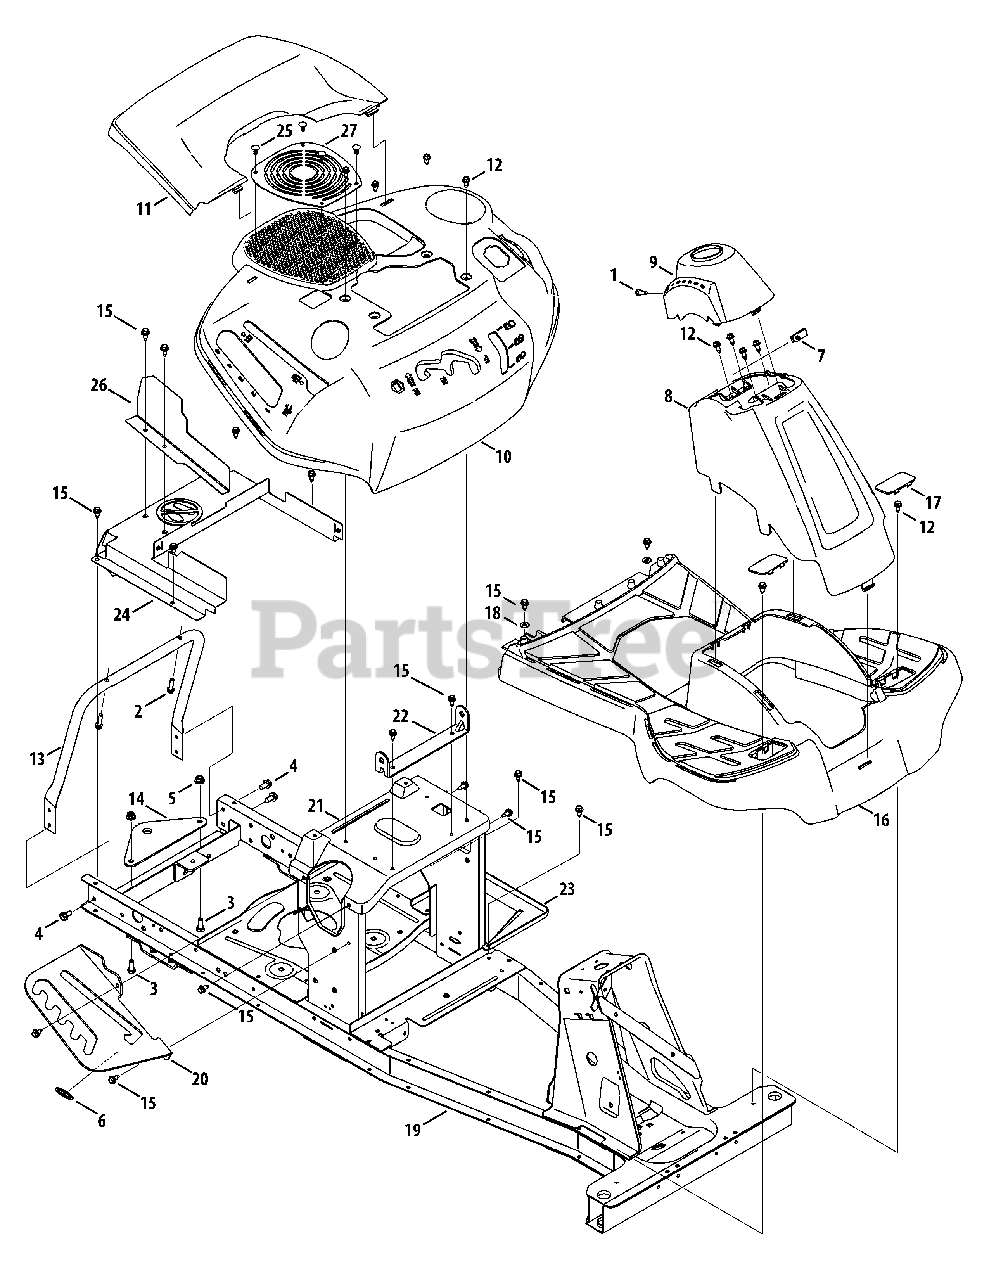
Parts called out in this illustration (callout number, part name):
1	Machine Screw, 1/4-20, 0.750
2	Hex Screw, 1/4-15, 1.000
3	Hex Head Screw, 5/16-18, .75
4	Tap Screw, 5/16-18, .750
5	Flange Locknut, 5/16-18
6	Speed Nut
7	U-type Speed Nut, 1/4-20
8	Column Cover
9	Steering Column Cap
10	Fender, (MTD Eng. 4P90JU)
11	Rear Cover
12	Shoulder Screw, .368 X.113: 1/4-20
13	Rear Cover Support Tube
14	Hitch Plate
15	Tap Screw, 1/4-20, .625
16	Running Board
17	Running Board Plug
18	Flat Washer, .250 x .630 x .052
19	Frame Assembly
20	Deck Lift Index Bracket
22	Seat Pivot Bracket
23	Battery Tray
24	Top Rear Drive Cover
25	Clip, .250 Dia., (MTD Eng. 4P90JUA)
26	Shield, (MTD Eng. 4P90JUA)
27	Screen Cover, (MTD Eng. 4P90JUA)
